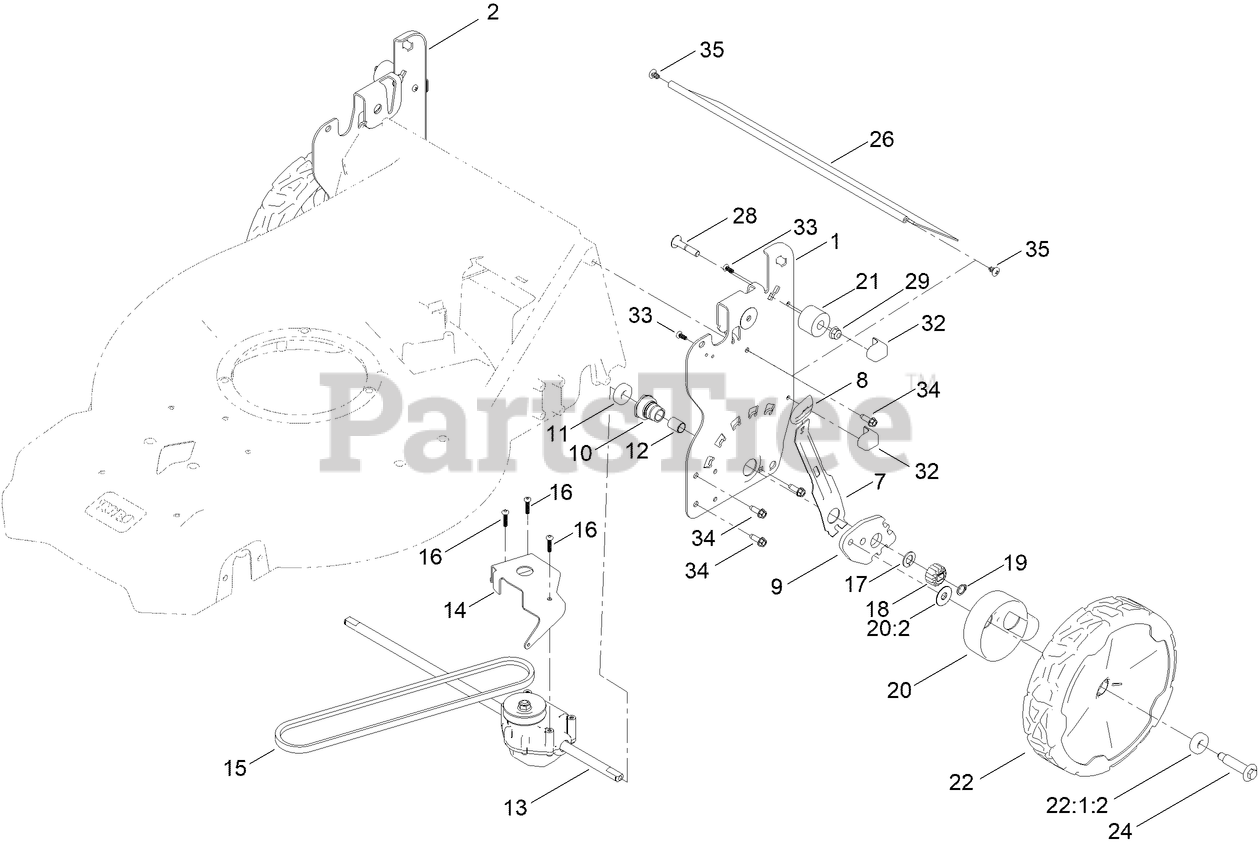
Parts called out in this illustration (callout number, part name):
1	PLATE-HOC, LH (ISO)
2	PLATE-HOC, RH (ISO)
7	ARM-SPRING
8	KNOB-LEVER, HOC
9	ARM-PIVOT, REAR
10	RETAINER-BUSHING, HOC
11	BEARING-WHEEL
12	BUSHING-SLEEVE
13	TRANSMISSION-RWD, 5.25:1
14	BRACKET-TRANS, RWD HI
15	BELT-V
16	SCREW-PLASTITE
17	WASHER-THRUST
18	GEAR-PINION, 15T
19	RING-RETAINING
20	ASM-COVER, GEAR
20:2	WASHER-STEPPED
21	BUMPER-ISOLATOR
22	ASM-9.65" WHEEL, GEARED
22:1:2	BEARING-WHEEL
24	WHEEL BOLT
26	SHIELD-TRAILING
28	SCREW-CARR-SPCL
29	NUT-HF, NI
32	PAD-SMART STOW
33	SCREW-PLASTITE
34	SCREW-HWHTF
35	SCREW-THD
